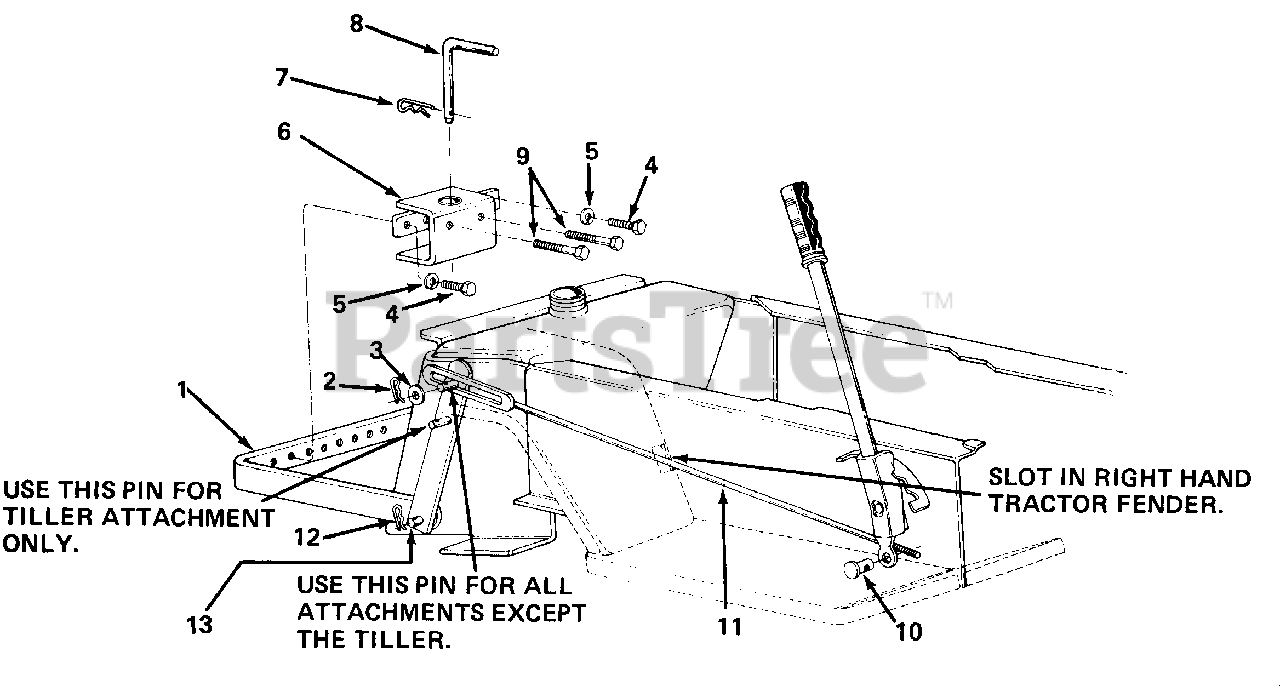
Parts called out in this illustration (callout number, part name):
3	Fl.-Wash. 1/2" I.D.
4	Hex Scr. 1/2-13 x 1.00" Lg.
5	L.-Wash. 1/2" Scr.
8	Hitch Pin
9	Hex Scr. 1/2-1 3 x 3.00 " Lg.
10	Adjustment Ferrule
13	Hitch Rod
